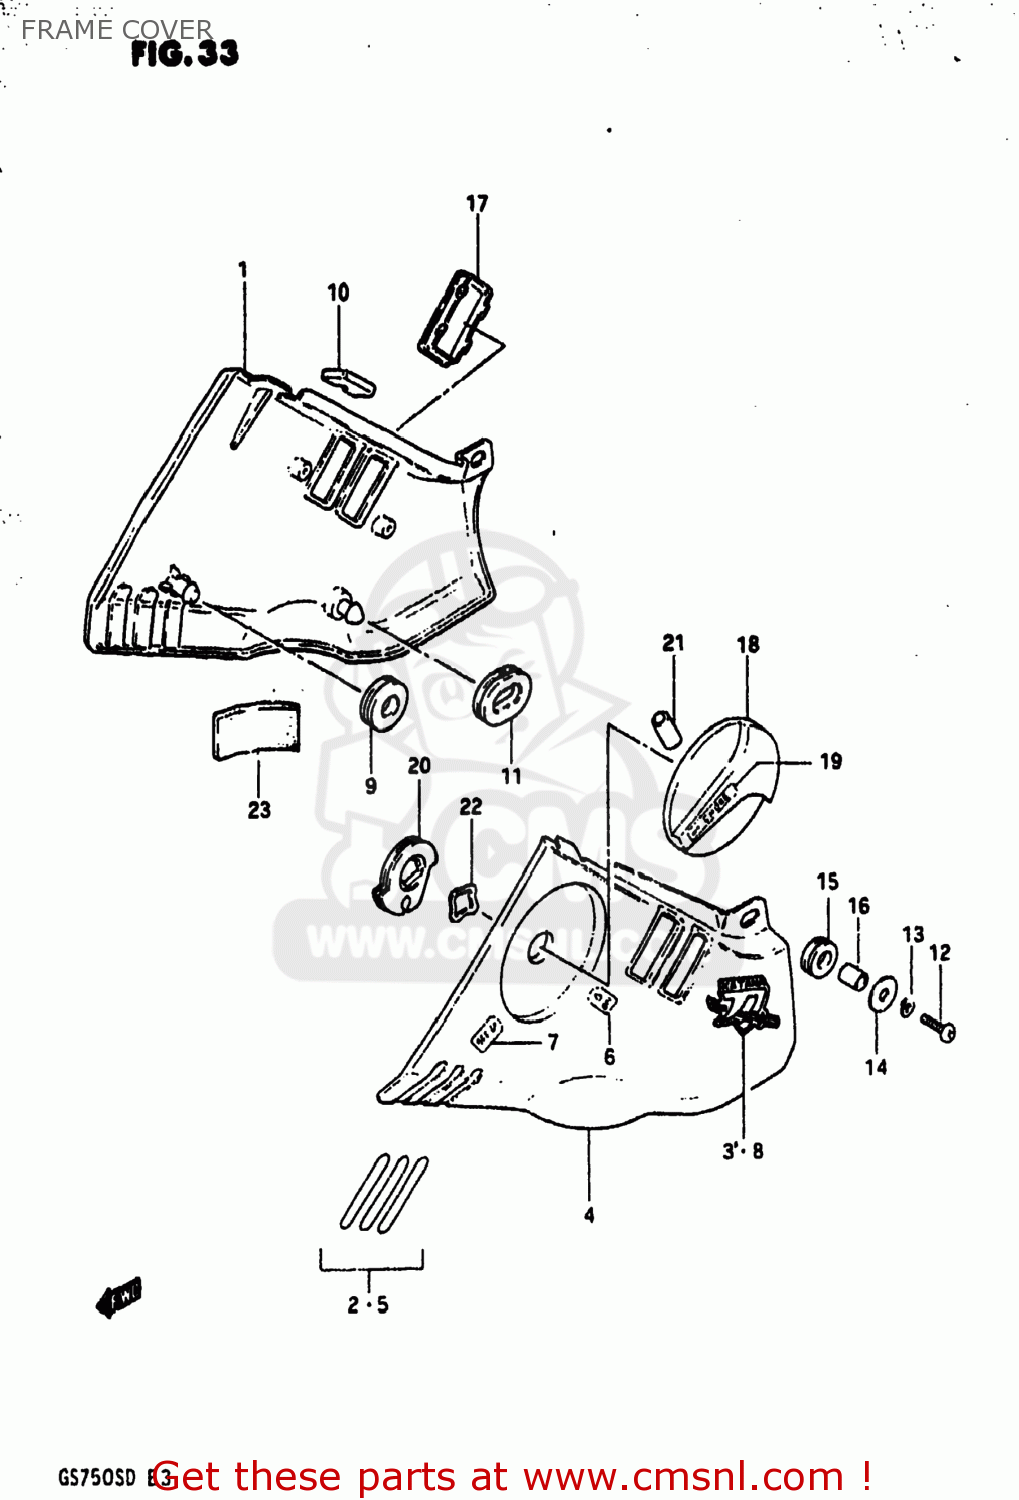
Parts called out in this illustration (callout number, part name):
1	COVER SET,FRAME,R(SILVER)
2	LABEL,FRAME COVER DENT
3	EMBLEM (KATANA)
4	COVER SET,FRAME,L(SILVER)
5	LABEL,FRAME COVER
6	LABEL,CHOKE ON
7	LABEL,CHOKE OFF
8	EMBLEM (KATANA)
9	CUSHION
10	CUSHION
11	CUSHION
12	SCREW
13	LOCK WASHER
14	WASHER
15	CUSHION
16	SPACER(6.1X9X7.5)
17	CAP,FRAME COVER SWITCH HOLE
18	LEVER,CHOKE CABLE
19	LABEL,CHOKE LEVER
20	HOLDER,STARTER CABLE
21	TUBE,CHOKE CABLE LEVER
22	WASHER
23	PAD
